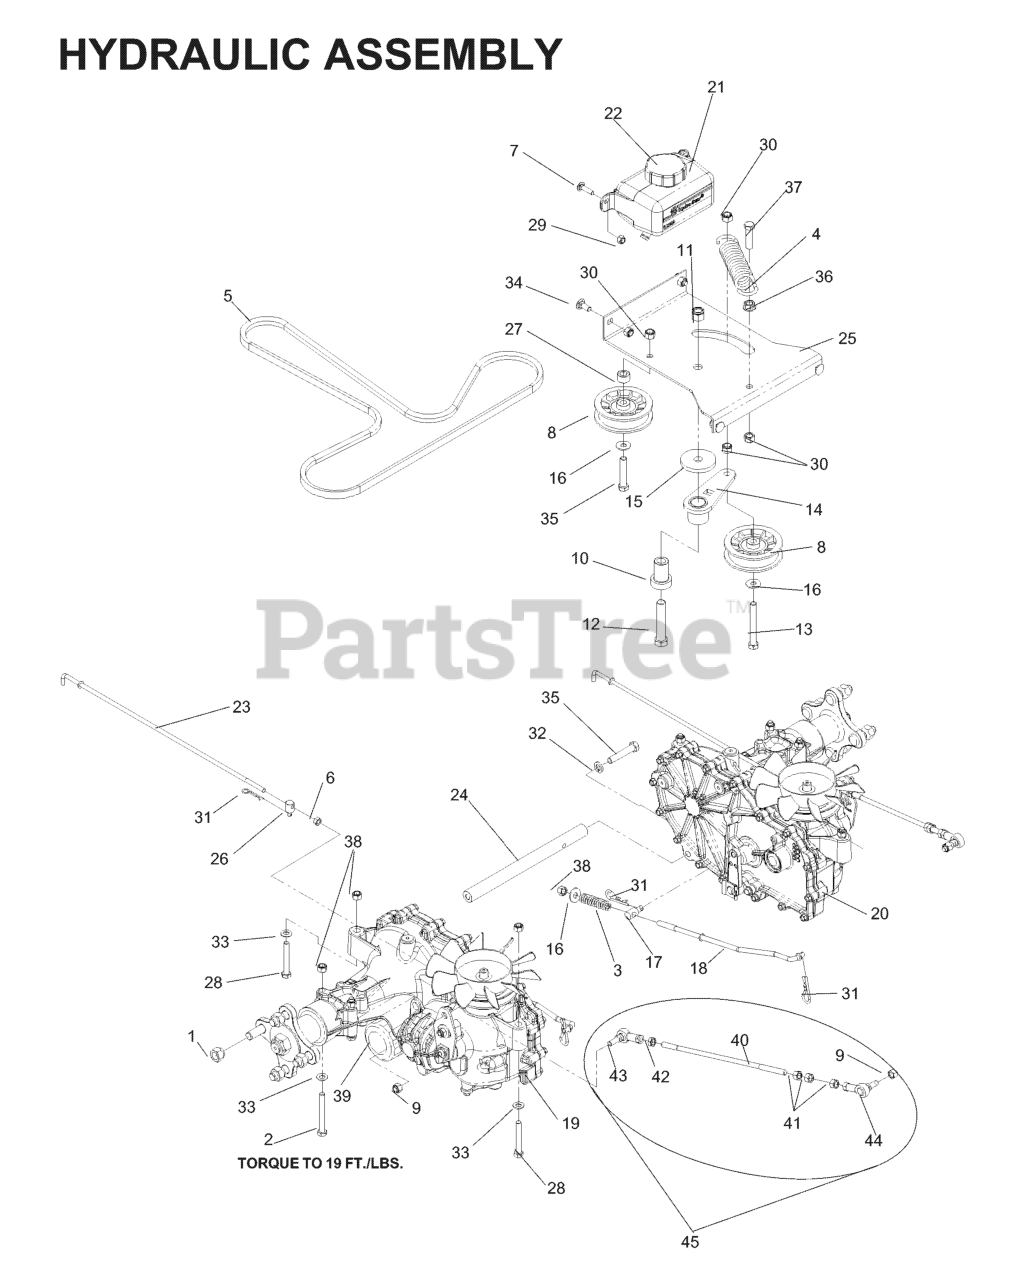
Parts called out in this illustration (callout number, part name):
1	LUG NUT 1/2F
2	HCS 5/16C X 2-3/4
3	HOSE, 3/8 HYDRAULIC 15 1/2" 90
5	PUMP BELT
6	NUT 1/4-28 HEX ZD
7	RHSNB, 1/4-20 X 1, GR5
8	PULLEY, IDLER RAKE & ZTR
9	NUT 5/16F NYLOC
10	IDLER SPINDLE
11	NUT 1/2-13 HEX NYLOC ZD
12	HCS 1/2C X 2 3/4
13	TAPBOLT, 3/8C X 3
14	RP.IDLER ARM WELDMENT
15	HEAVY WASHER
16	WASHER 5/16 FLAT
17	BRAKE SWIVEL
18	BRAKE LINKAGE, LOWER
19	HG_ZT2800 RIGHT SIDE
20	HG_ZT2800 LEFT SIDE
21	HG_EXPANSION TANK W/CAP 71354
22	HG_CAP 52375
23	BYPASS LINKAGE
24	2800 CROSS SUPPORT
25	IDLER PULLEY PLATE
26	SWIVEL, 1/4-28
29	NUT.1/4-20.HEX.NYLOC.ZD
30	NUT 3/8-16 NYLOC
31	HAIRPIN #2
32	SLW 3/8 STD
33	FLAT WASHER 5/16 SAE
34	BOLT 5/16C X 3/4" CARRIAGE
35	HCS 3/8C X 2
36	NUT 3/8C WHIZ
37	HCS 3/8C X 1 1/2
38	NUT 5/16 NYLOC
39	HG_FILTER, ZT4800 52114
40	DRIVE LINKAGE
42	NUT 5/16F LEFTHAND
43	SPHERICAL ROD END, LH
44	SPHERICAL ROD END, RH
45	LINKAGE, DRIVE EZ IZT
